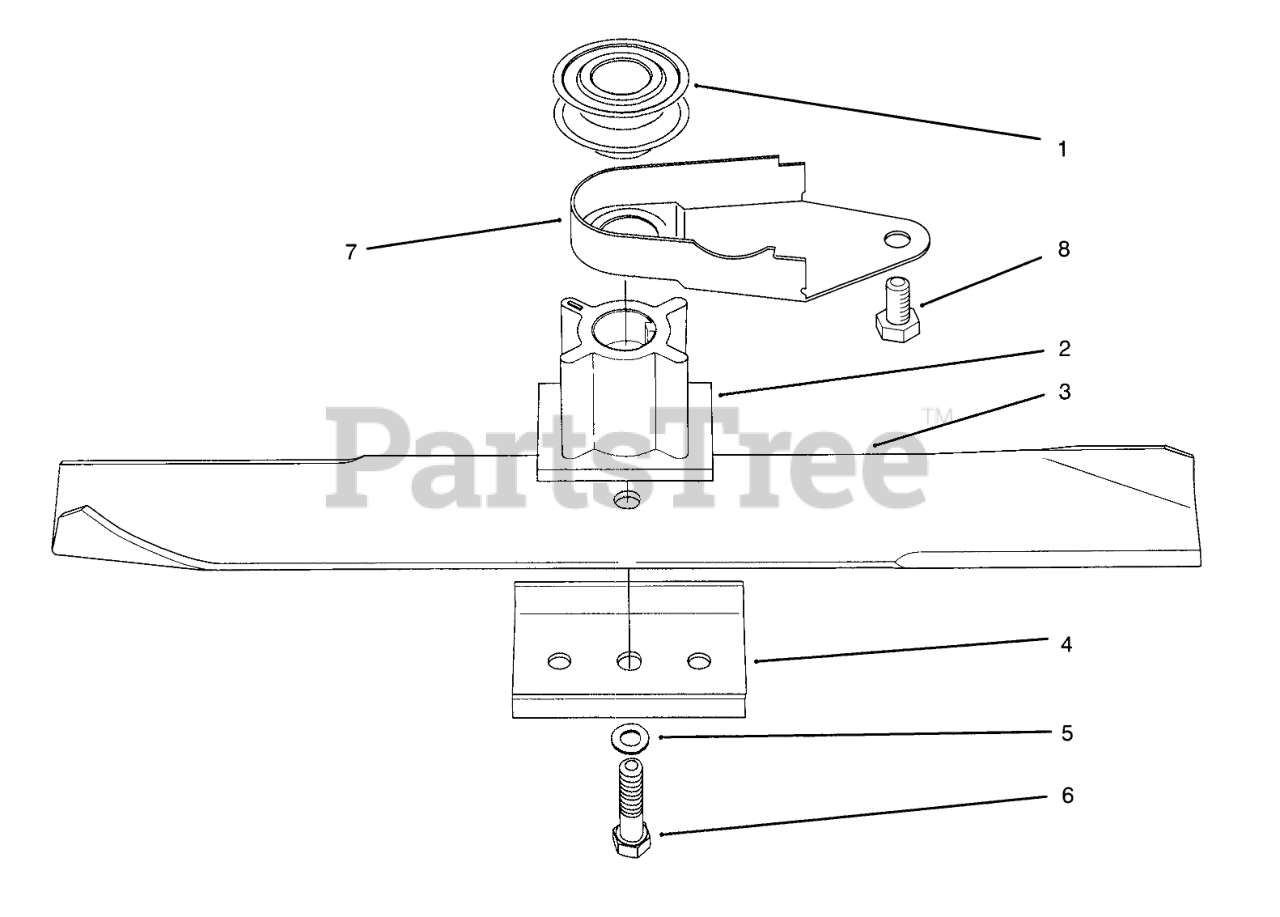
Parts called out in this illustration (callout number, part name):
1	PULLEY-DRIVE, ZONE START
2	RETAINER-BLADE
3	Blade-43cm
4	STIFFENER - BLADE
5	WASHER-LOCK
6	BOLT-BLADE
7	COVER-GUIDE, BELT
8	SCREW-COVER, BELT
